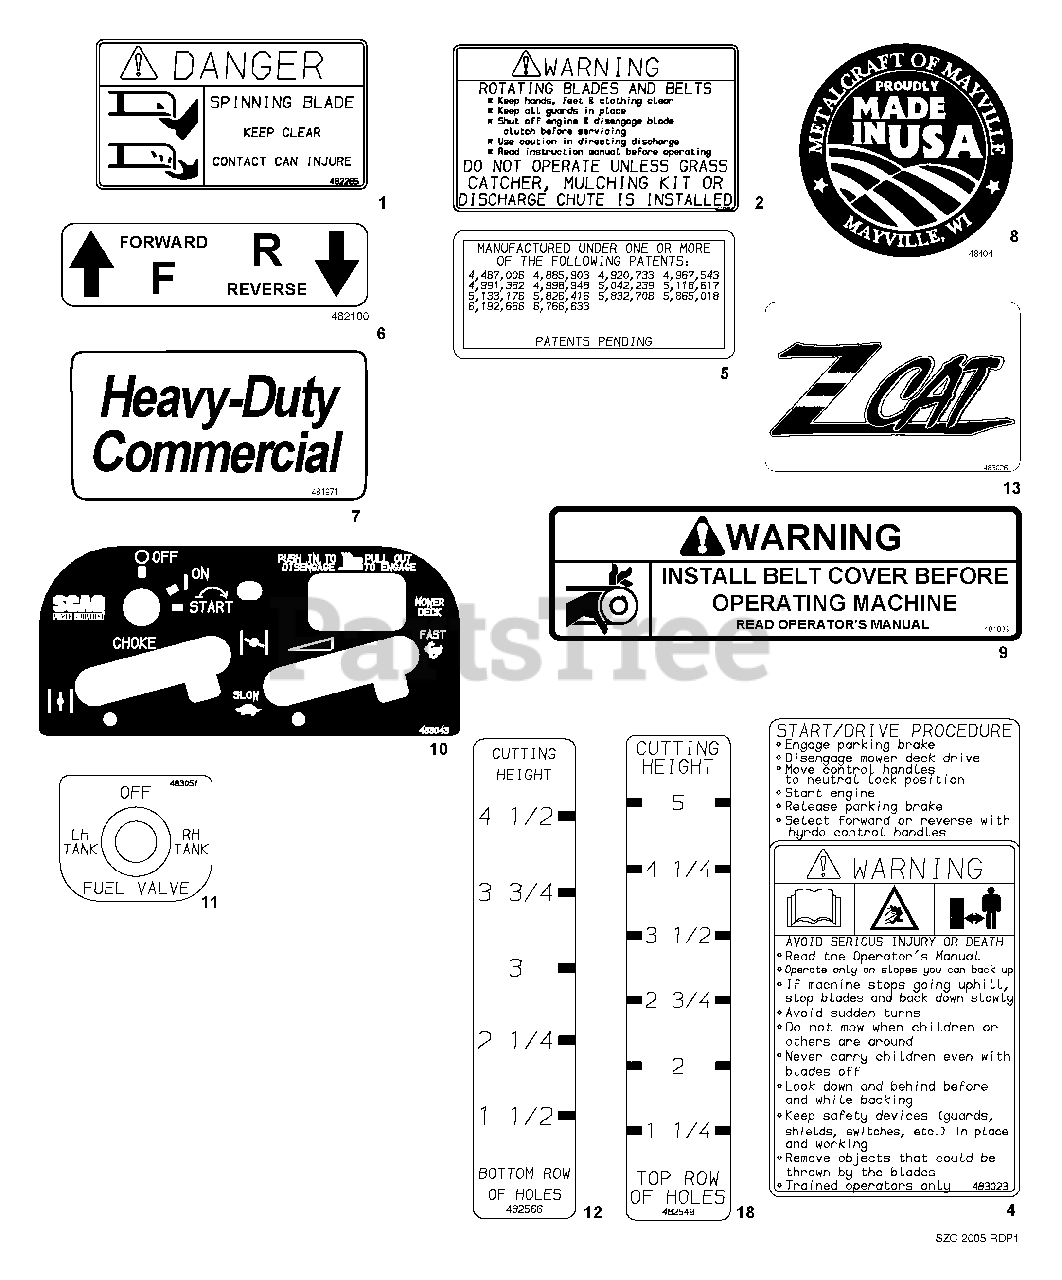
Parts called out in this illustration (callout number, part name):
1	Decal, Danger-Spinning Blades
2	Decal, Warning-Rotating Blades
4	Decal, Fuel Tank Start/Drive
5	Decal, Patents
6	Decal, Traction Control
7	Decal, Heavy Duty Commercial
8	Decal, Metalcraft - Made in USA
9	Decal, Belt Cover
10	Decal, Instrument Panel
11	Decal, Fuel Shutoff
12	Decal, Cutting Height Bottom Row of Holes
13	Decal, Front SZC
18	Decal, Cutting Height Top Row of Holes
